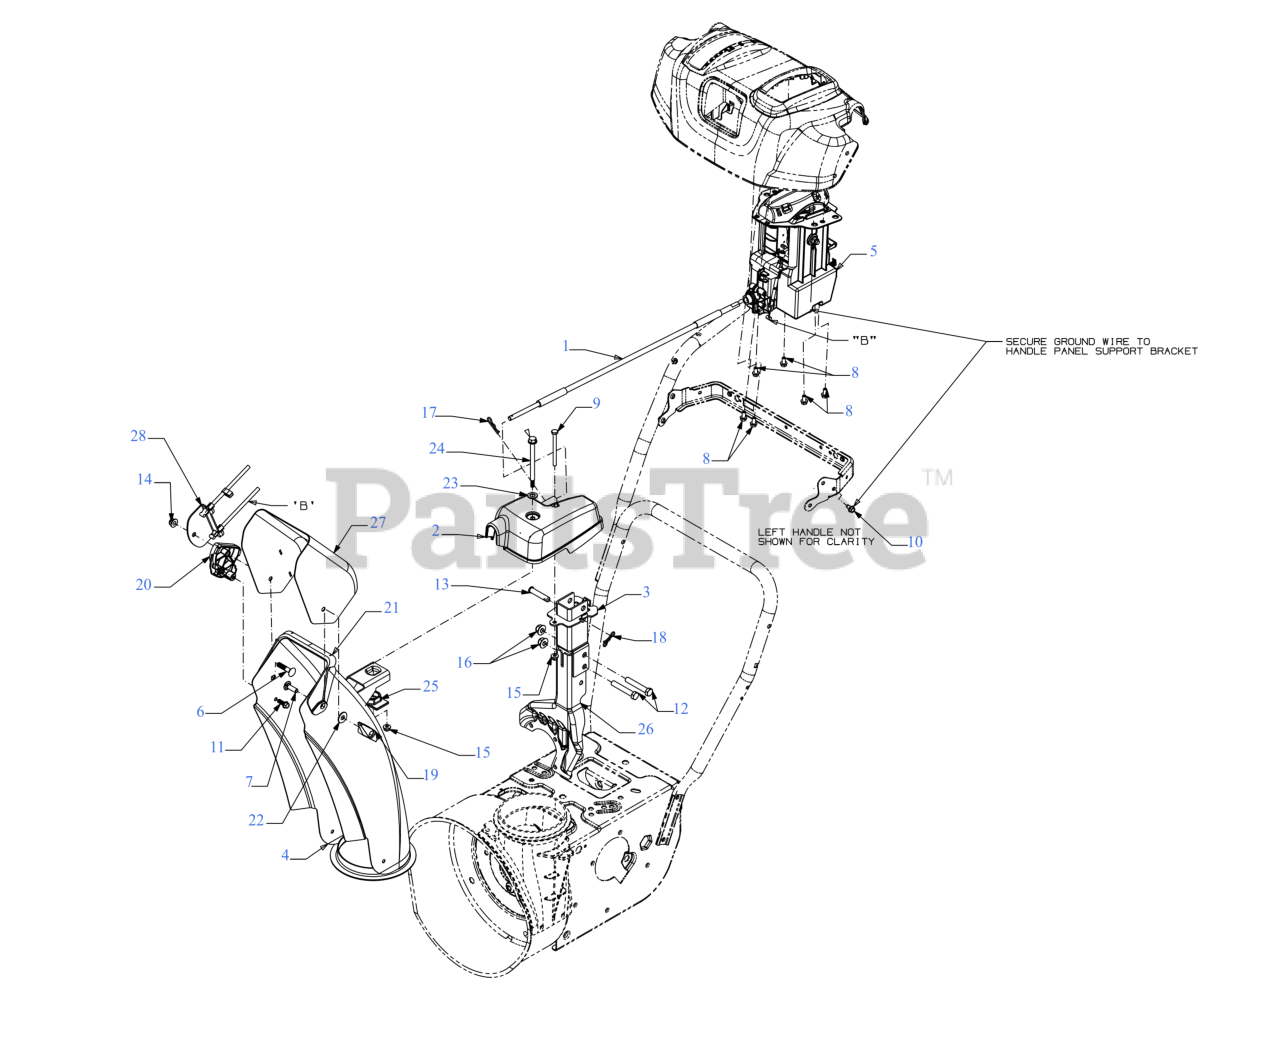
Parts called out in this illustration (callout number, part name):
1	ELECTRIC 4-WAY CONTROL SHAFT
2	WORM GEARBOX ASSEMBLY
5	CHUTE CONTROL ASSEMBLY-4-WAY ELECTRIC
6	CARRIAGE BOLT 5/16-18 x 1.50
7	CARRIAGE BOLT 5/16-18 x 1.00
8	HEX SCREW 1/4-15 x .50
9	SCREW 1/4-20 x 3.0 GR5
10	SCREW 1/4-20 X.500
11	SCREW 1/4-15 x .750
12	SCREW 3/8-16 x 2.25 GR5
13	CLEVIS PIN 3/8 x 1.87
14	FLANGE LOCK NUT 5/16-18
15	FLANGE LOCK NUT
17	INTERNAL COTTER PIN
18	BOW TIE COTTER PIN 1/4-5/16
19	WING NUT KNOB
20	CHUTE TILT GUIDE
21	UPPER CHUTE ADAPTER
22	FLAT WASHER
23	FLAT WASHER
24	SHOULDER SCREW
25	HELICAL GEAR CHUTE ADAPTER
